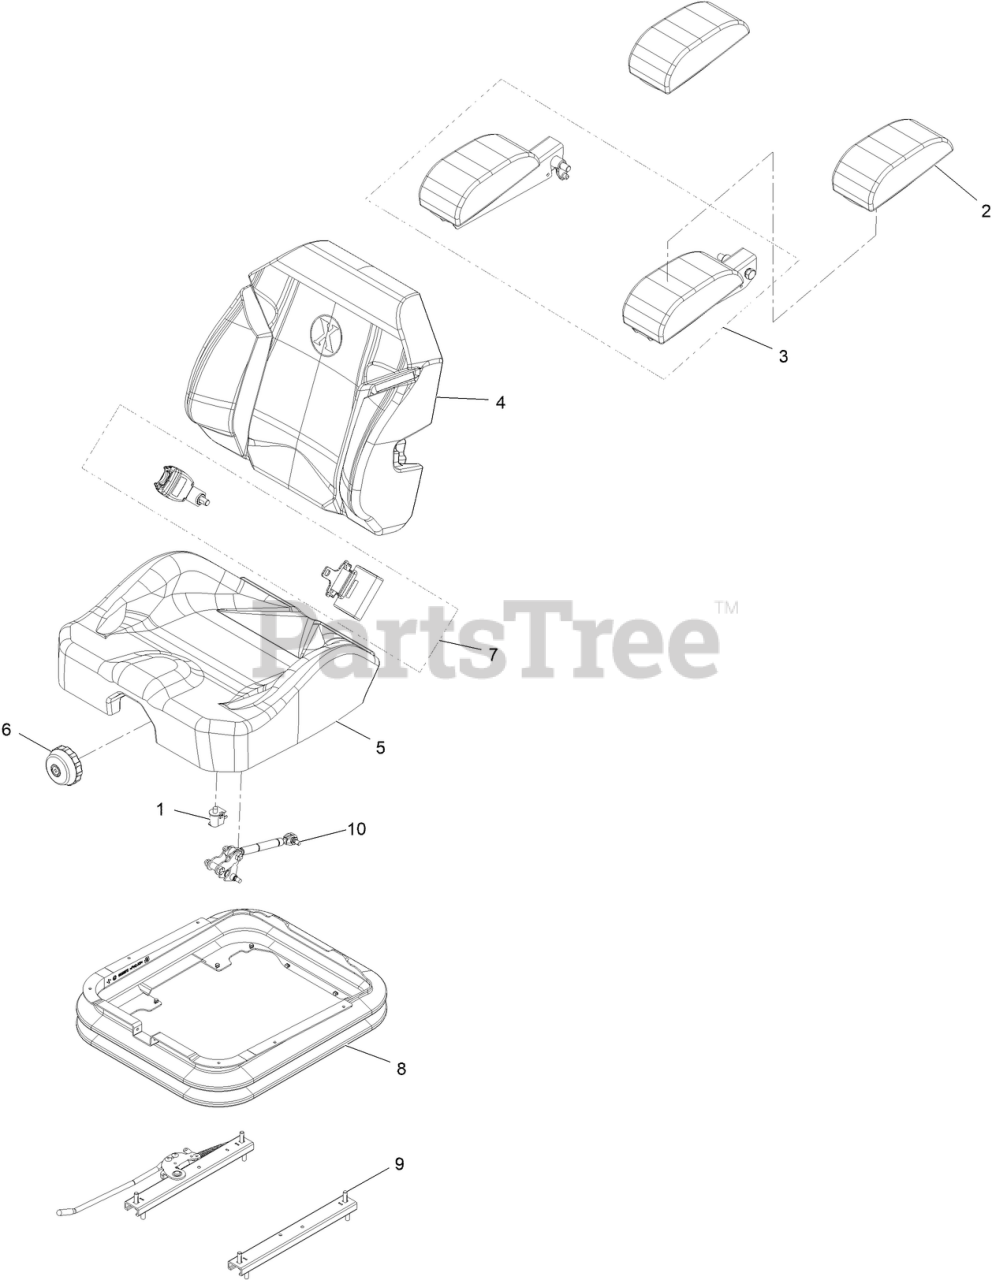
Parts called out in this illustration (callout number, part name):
1	SWITCH-BAIL
2	KIT-ARM REST PADS
3	KIT-ARM REST SET
4	COVER-BACK 311463VN500
5	COVER-CUSHION
6	KNOB-ADJUSTER
7	KIT-SEAT BELT
8	COVER-SUSPENSION BELLOWS
9	SET-SEAT TRACK
10	DAMPER-SEAT
